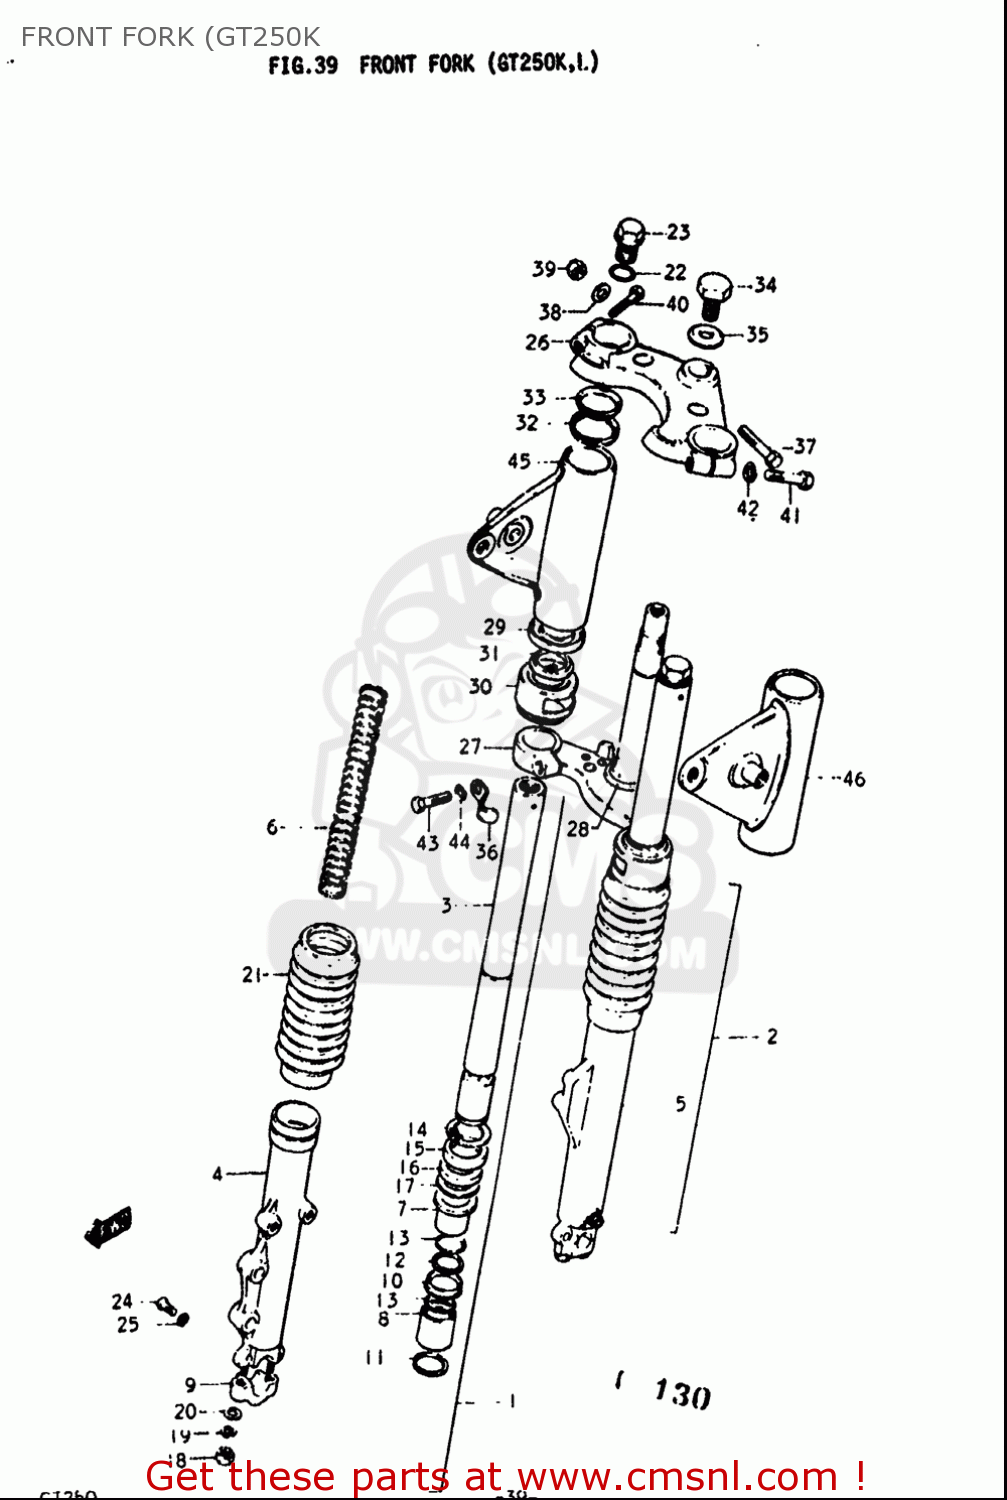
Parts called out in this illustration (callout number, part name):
9	HOLDER,AXLE
15	SEAL,OIL
18	NUT
19	WASHER,LOCK
20	WASHER
21	BOOT
24	SCREW 4X6
25	GASKET (NAS)
28	RACE,STEERING OUTER LWR
29	GUIDE
31	CUSHION,HEADLAMP BRACKET
32	GUIDE
33	CUSHION,HEADLAMP BRACKET UPR
36	LAMP ASSEMBLY
37	BOLT
38	WASHER
39	NUT
41	BOLT
42	WASHER,LOCK
43	BOLT
44	WASHER,LOCK
